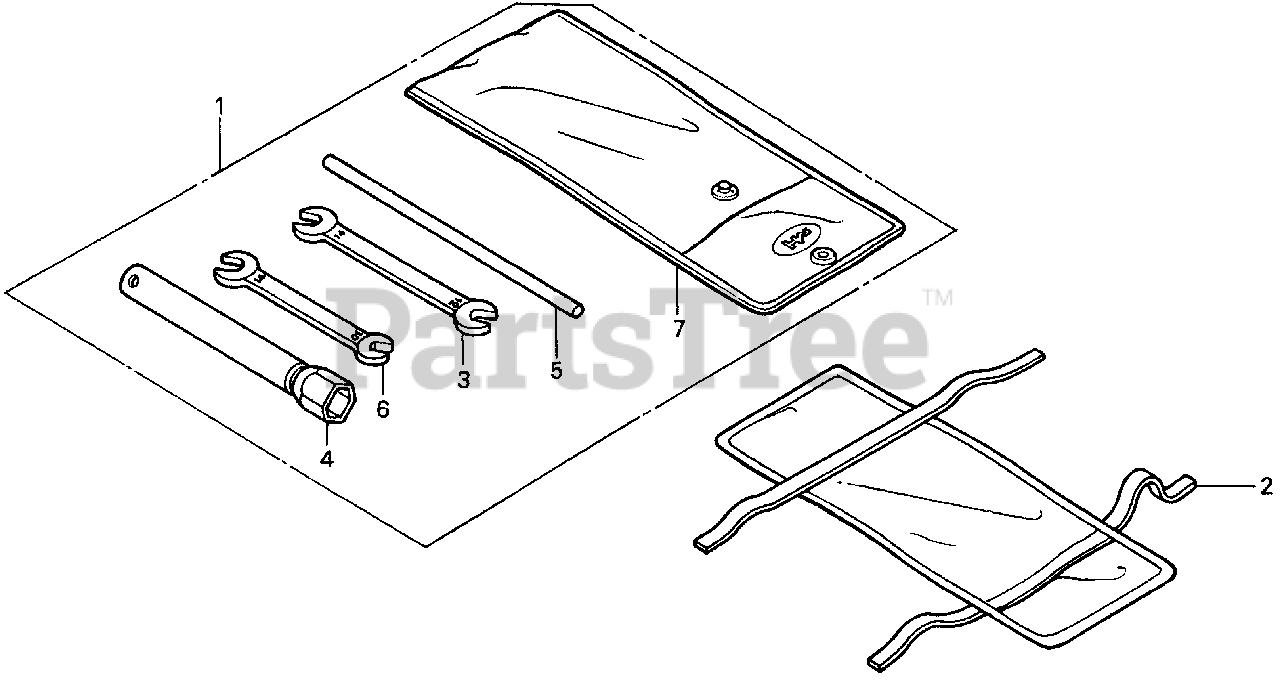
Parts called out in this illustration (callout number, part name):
3	SPANNER (12X14)
4	WRENCH, SPARK PLUG
5	HANDLE, BOX WRENCH
6	WRENCH (10X14) (OPEN END)
